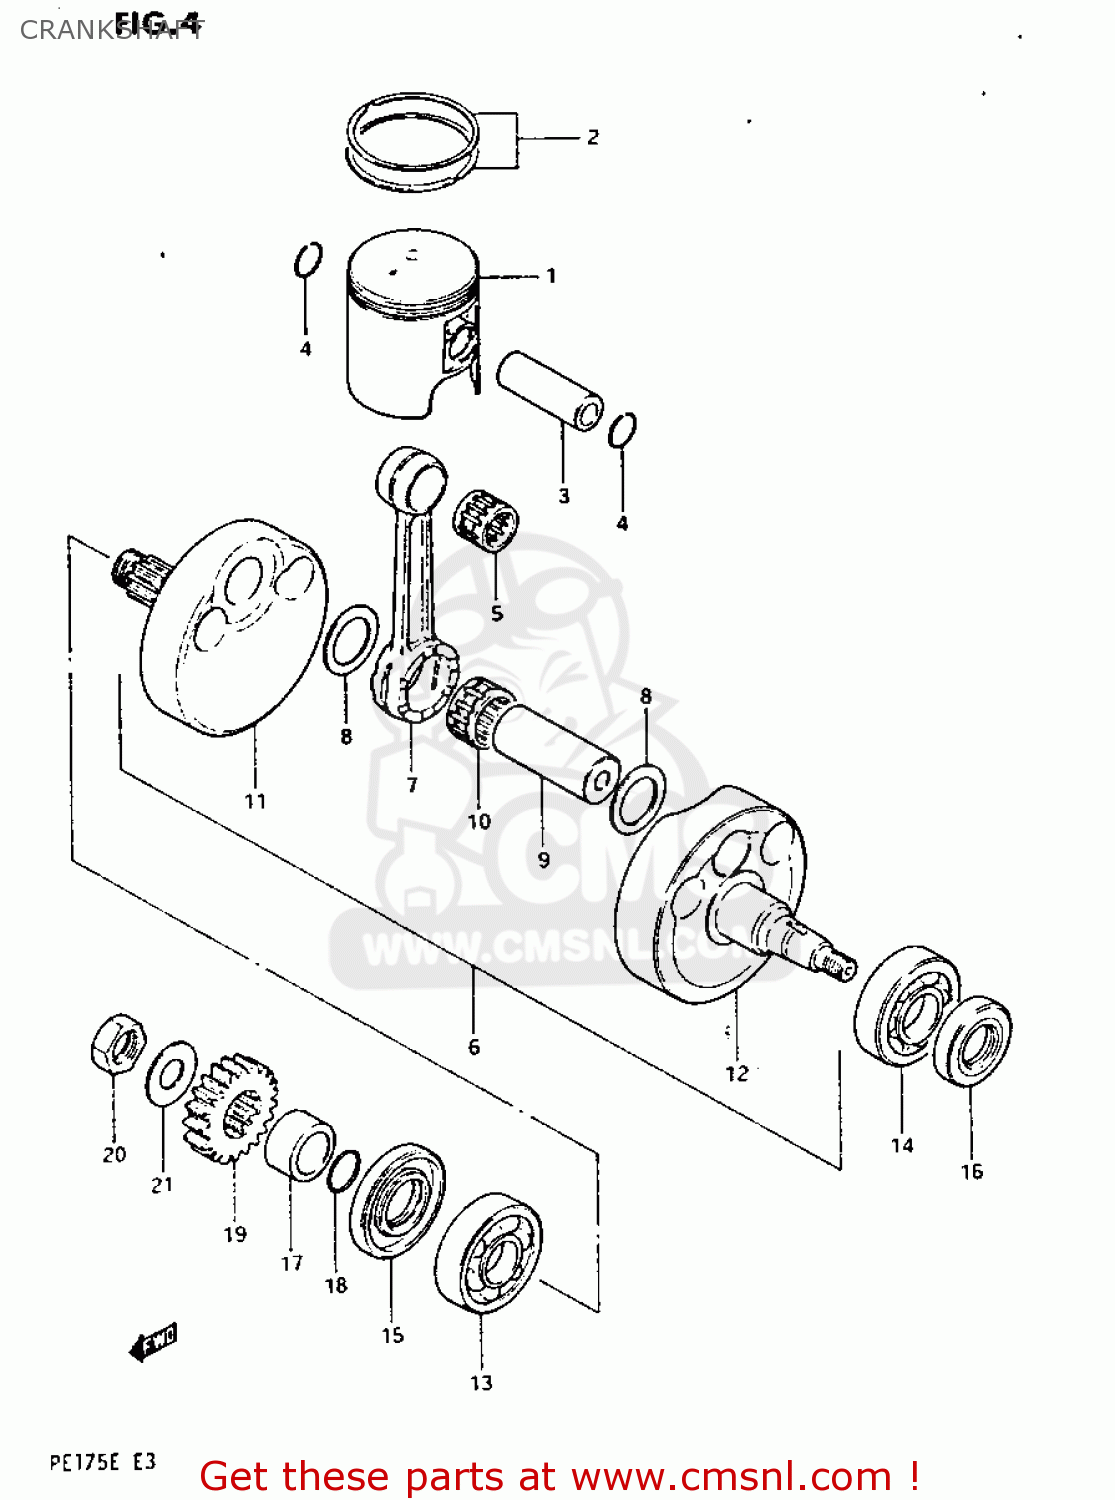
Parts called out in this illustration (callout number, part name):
1	PISTON
2	RING SET,PISTON
3	PIN,PISTON
4	RING,SNAP 16MM
5	BEARING
6	CRANKSHAFT ASSEMBLY
7	ROD,CONNECTING
8	WASHER(22X35X1)
9	PIN,CRANK
10	BEARING(22X28X16)
11	CRANKSHAFT
12	CRANKSHAFT,LEFT
13	BEARING(22X56X16)
14	BEARING(25X52X15)
15	SEAL,OIL(29X47X8)
16	SEAL,OIL(25X44X7)
17	SPACER
18	O RING(D:2.4,ID:19.8)
19	GEAR,PRIMARY DRIVE
20	NUT
21	WASHER
